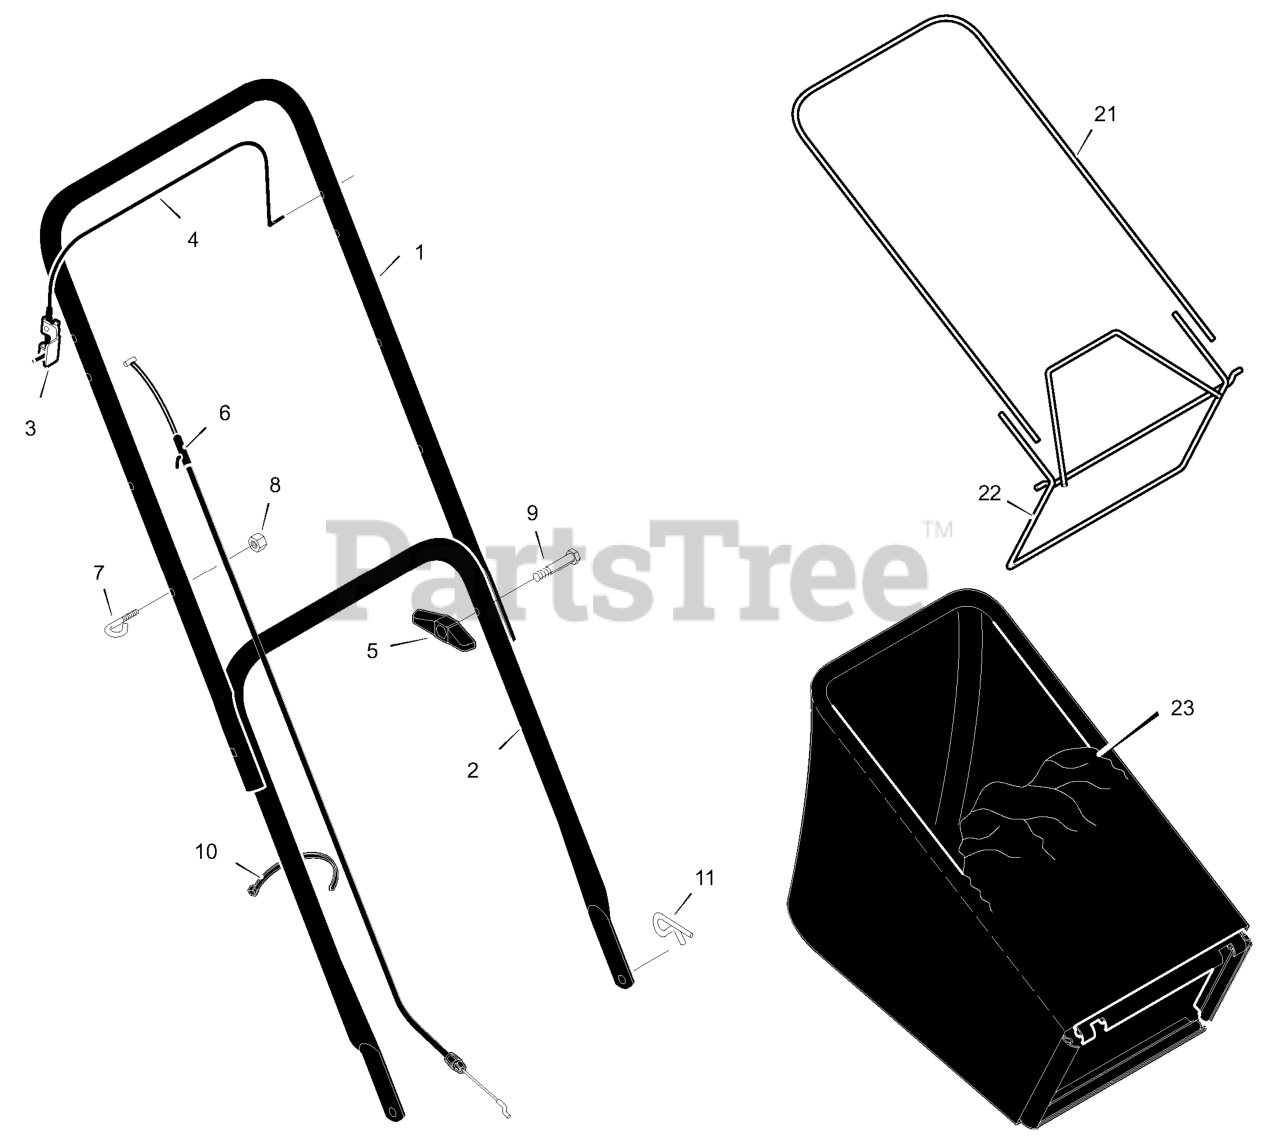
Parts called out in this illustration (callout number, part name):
1	Handle, Upper
2	Handle, Lower
4	Knob, Plastic
7	Locknut
12	Guide, Rope
13	Engine Stop Lever
14	Bracket, Stop Lever
15	Fastener, Cable
16	Engine Stop Cable
17	Hair Pin
21	Frame, Top
22	Frame Assembly
23	Bag, Cloth
